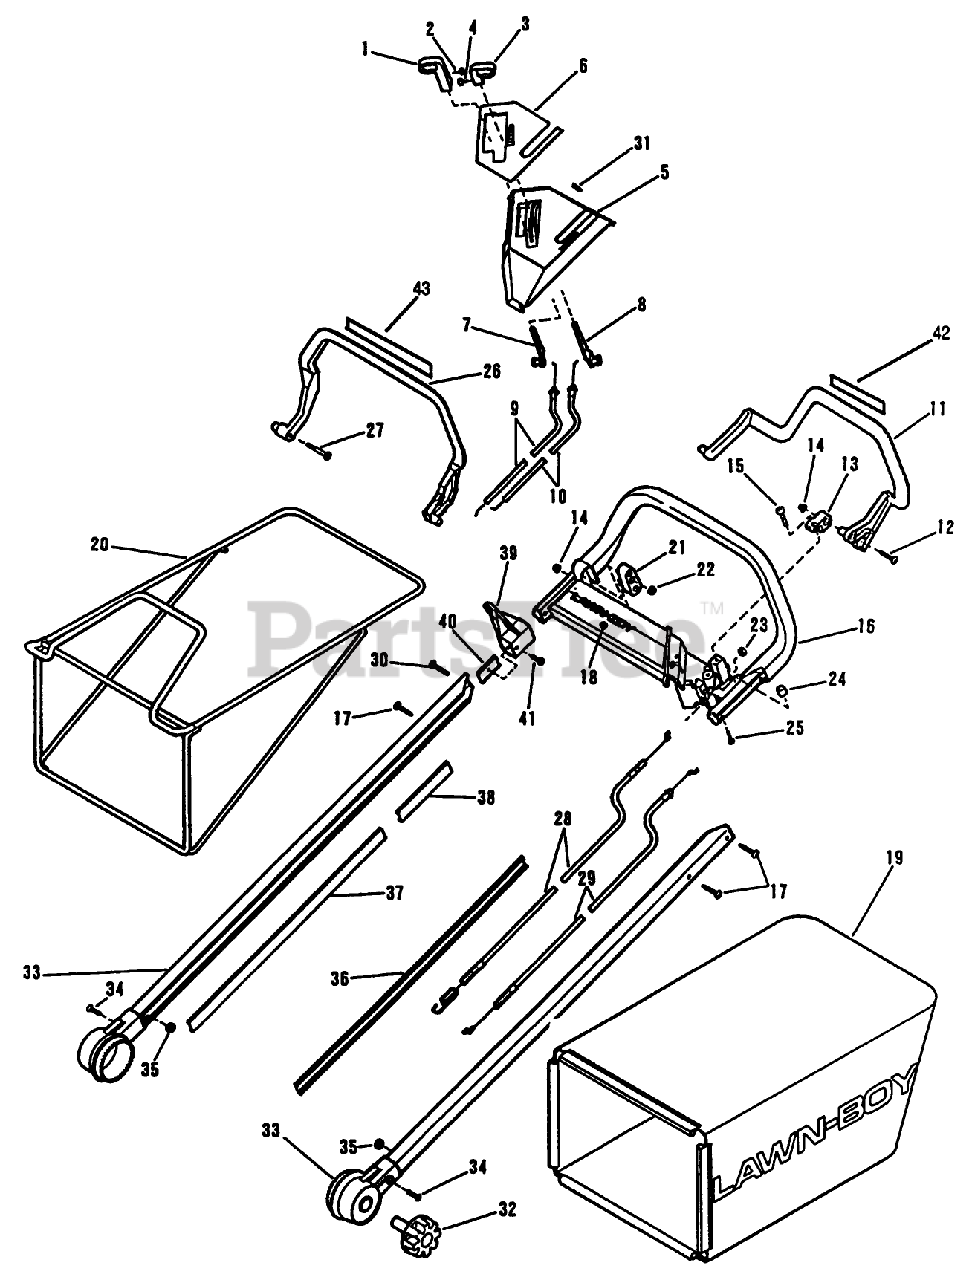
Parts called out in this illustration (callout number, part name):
1	KNOB & SCREW AY
5	UPPER CVR&DECAL AY
9	CABLE AY. WESCON
10	CABLE
11	BAIL-S.P. *
13	PIVOT BAIL PL
14	LOCKNUT FLAN
17	SCREW
21	BLOCK BAIL PL
22	LOCKNUT E
29	CABLE ASSEMBLY
30	SCREW-TRUSS
32	KNOB-HDLE MT.ASM*B
35	LOCKNUT FLAN
40	NUT LB
43	DECAL-ZONE
